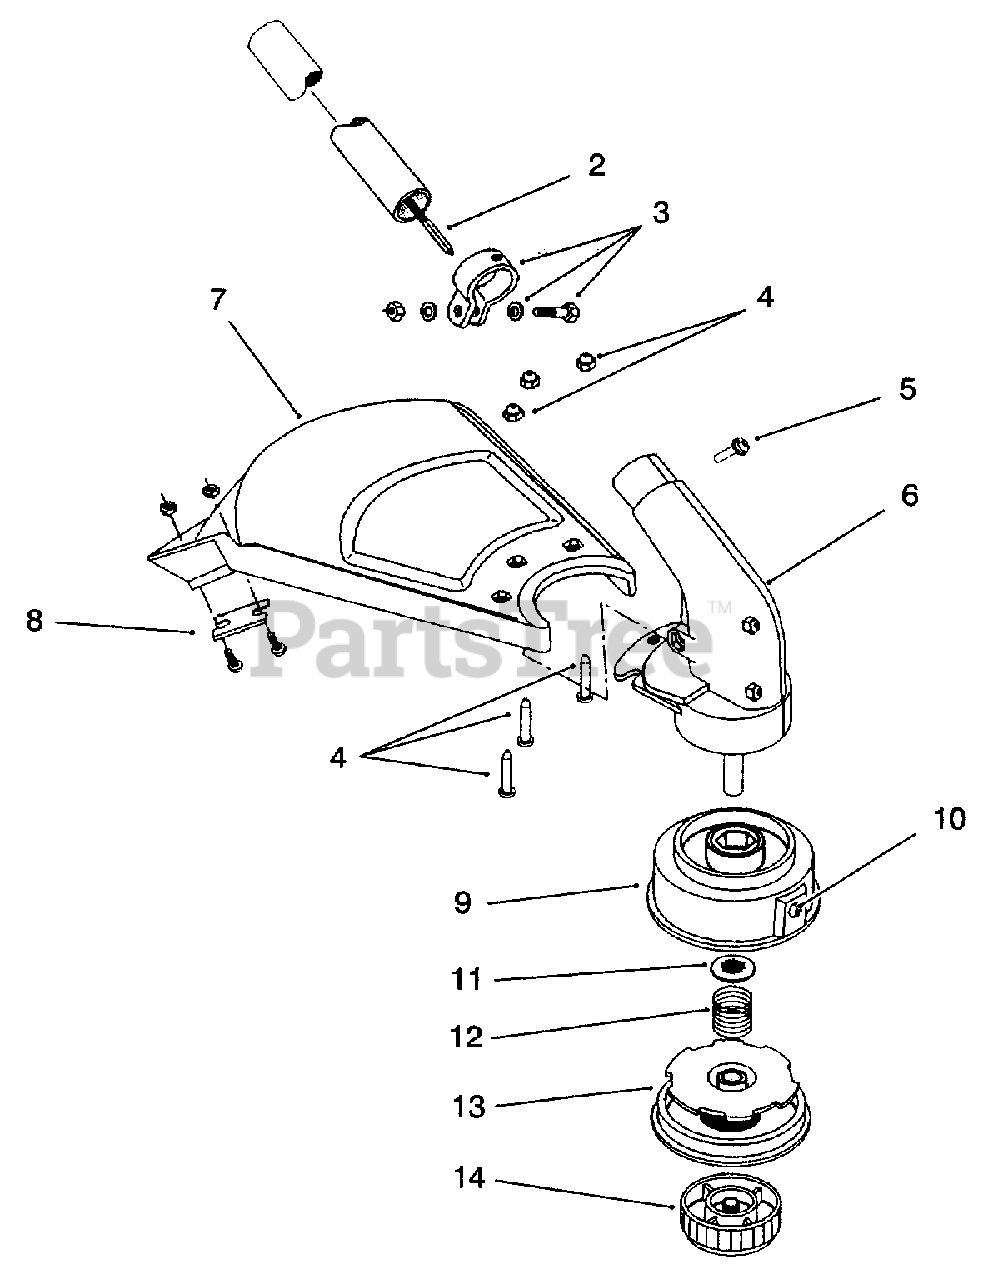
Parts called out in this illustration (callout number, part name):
1	Drive Shaft Housing Asm.
2	Shaft-Flexible Drive
3	Clamp Assembly
4	Hardware-Guard Mounting
5	Screw-Anti-Rotation
6	Gearbox
7	Guard-Cutting Head (Incl. Ref. #8)
8	Blade Assembly
9	Spool-Outer W/Eyelet (Incl. Ref. #10)
11	Retainer
13	Reel-Inner
14	Bump Head Knob Assembly
